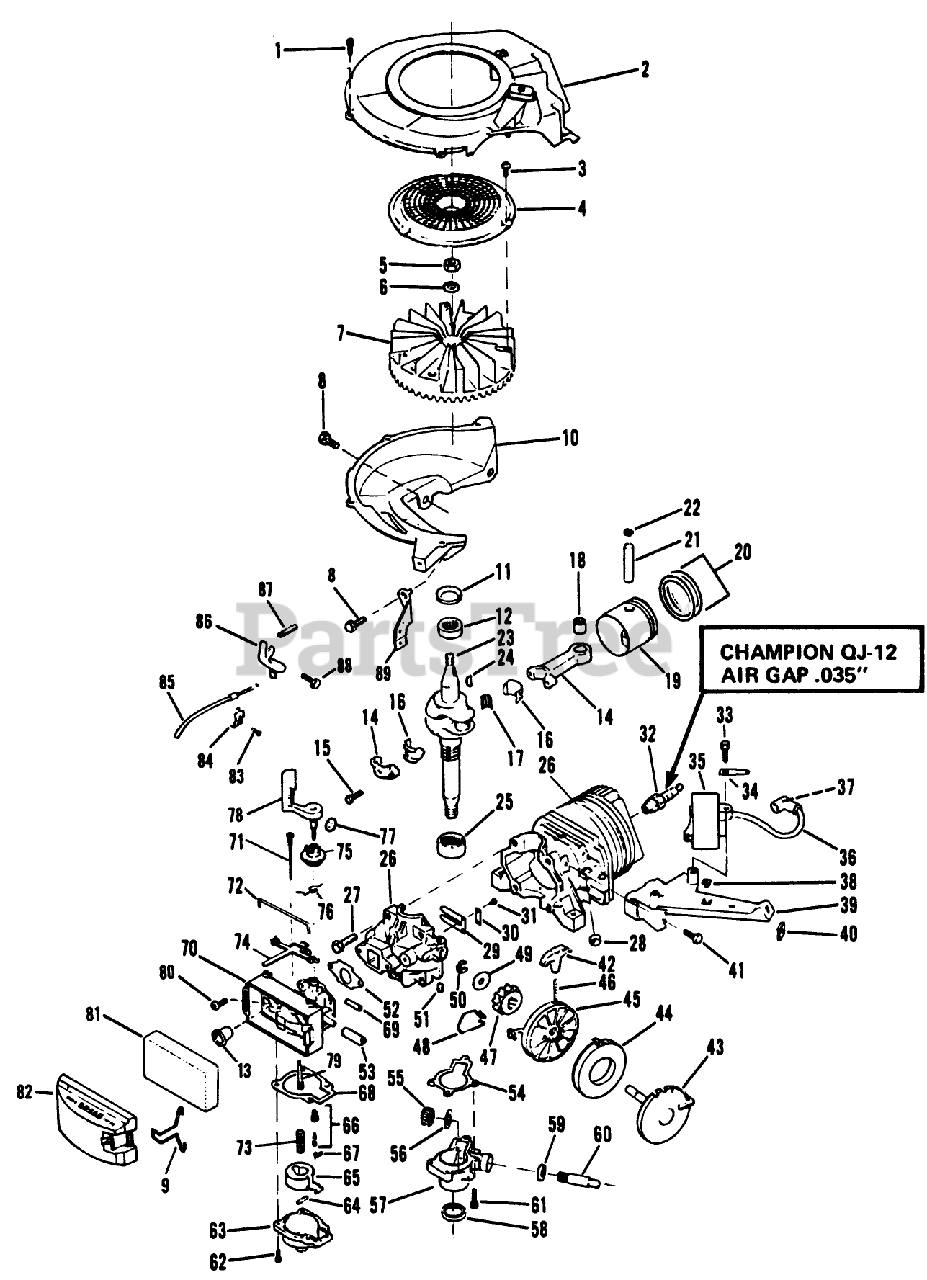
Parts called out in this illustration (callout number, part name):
1	SCREW S
2	AIR BAF&EYELET S
3	SCREW F
5	NUT
8	SCREW-SEMS
9	RETAINER-COVER, FILTER
10	SHROUD BASE S
12	BEARING V
15	SCREW-HSH
16	LINER ASM
18	BEARING AY F
22	RING-RETAINING
24	KEY
25	BEARING S
27	SCREW S
28	PLUG-CORE VF
30	PLATE-BACKUP, REED
34	TERMINAL S
36	HT LEAD&COVER XEV
38	NUT-CLIP
40	NUT - SPEED S
42	HANDLE STARTER S
46	PULLEY STARTER S
48	SPRING F
49	WASHER S
52	GASKET CARB S
54	GASKET S
55	GEAR, DR SHAFT S
56	THRUST WASHER
58	SEAL-OIL
59	SEAL S
62	SCREW-HH
69	TUBING PRIMER S
70	CARB BODY S
71	NEEDLE ADJ. AY S
72	RETAINER
73	FILTER-FUEL VS
74	LEVER S
75	COLLAR-ADJUST, AIRVANE
76	SPRING,THROTTLE S
77	DISC S
78	AIR VANE&SHAFT S
80	SCREW
84	CLIP S
86	LEVER LOCKOUT S
88	BOLT S
